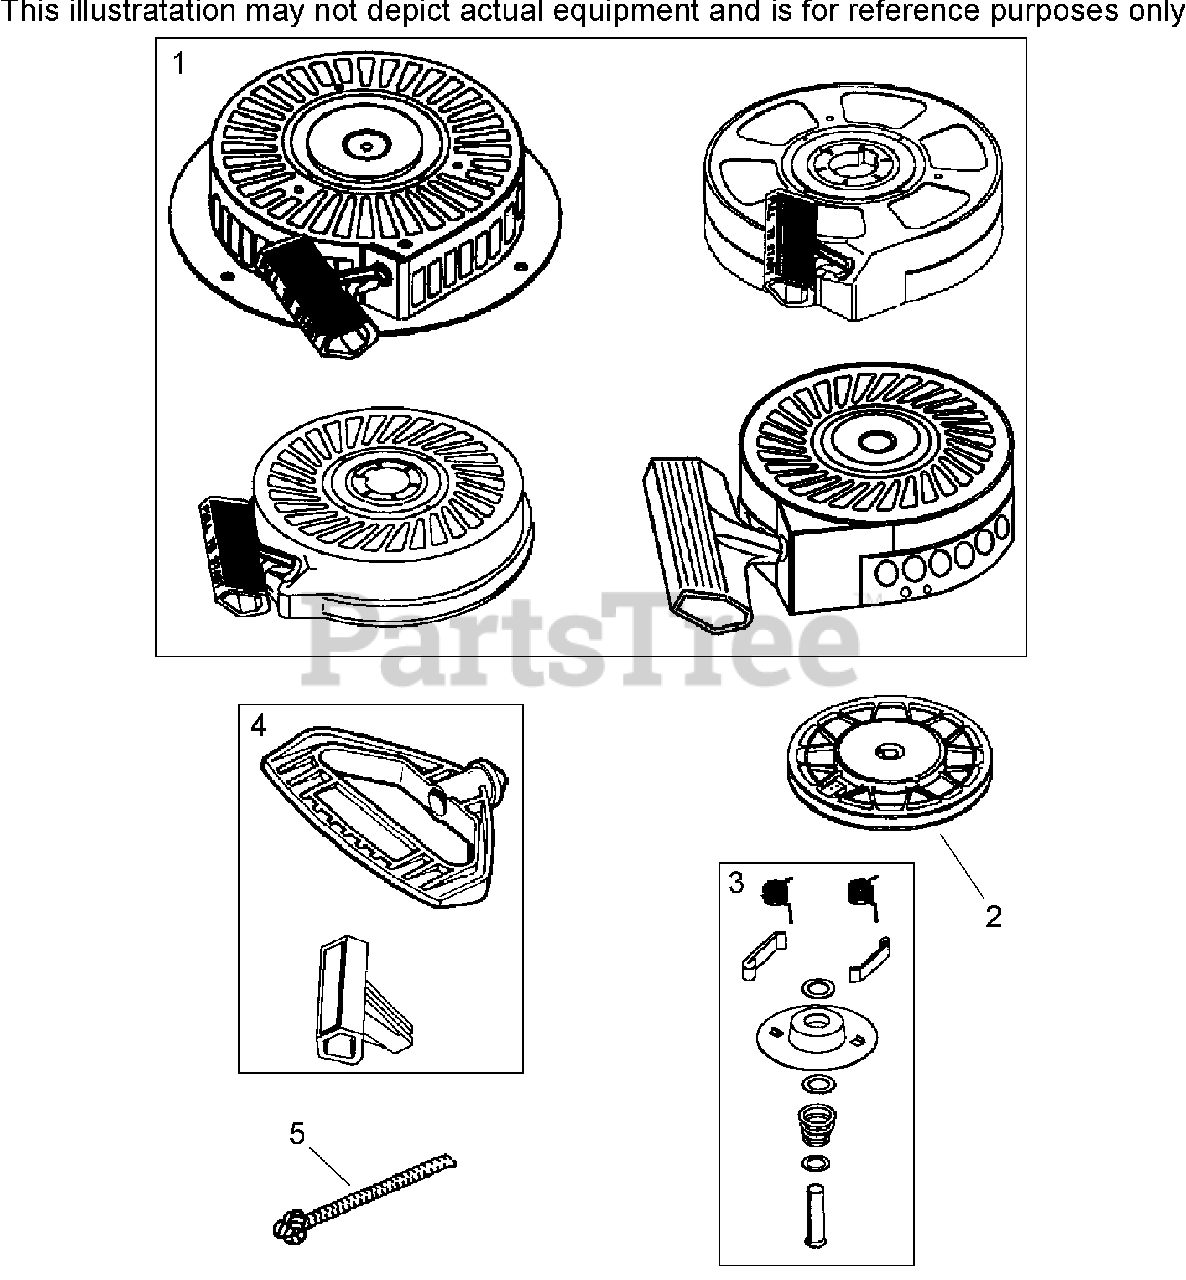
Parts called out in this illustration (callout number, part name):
1	Starter-Recoil
2	Pulley and Rewind Spring ASM
3	Repair Kit
4	Handle-Starter
5	98 Starter Rope (cut to length)
